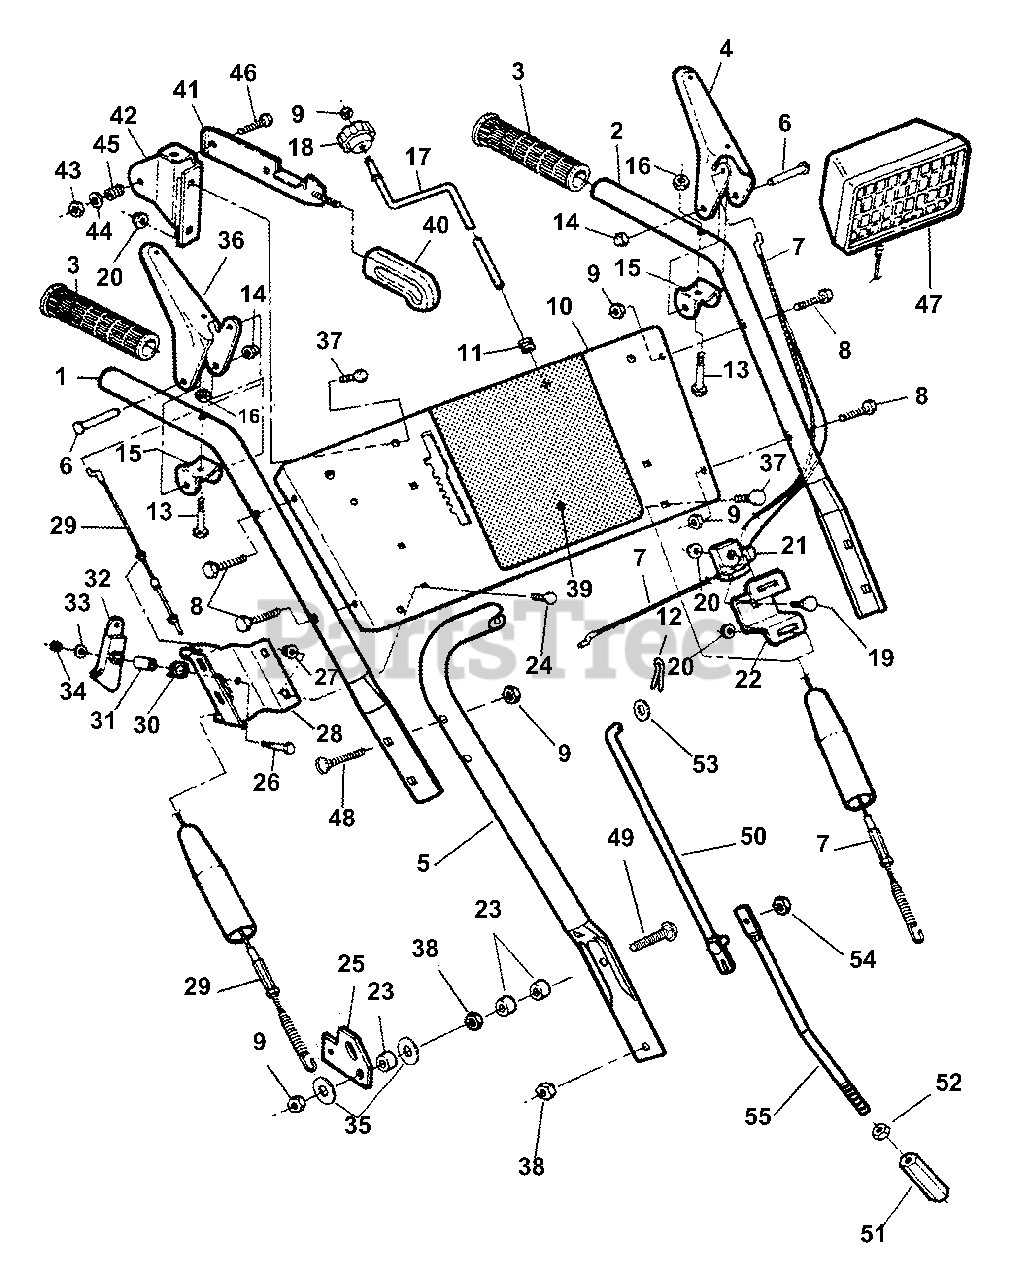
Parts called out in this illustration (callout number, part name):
1	BAR, Handle (Right Side)
2	BAR, Handle (Left Side)
3	GRIP, Handle
4	HANDLE, Left Side
5	HANDLE BAR, Lower
6	PIN, 1/4 x 1-7/8" Clevis
7	CABLE, Left Side Clutch
8	SCREW, 5/16-18 x 1-1/2" Hex Head Cap, Grade 5
9	NUT, 5/16-18 Hex Center Lock, Grade B
10	PANEL, Control
11	BUSHING
12	PIN, 1/8 x 1" Cotter
13	SCREW, 1/4-28 x 1-3/8" Hex Head Cap, Grade 5
14	NUT, 1/4" Push
15	BRACKET, Handle
16	NUT, 1/4-28 Hex Top Lock
17	CRANK, Chute
18	KNOB, Chute Crank
19	BOLT, 1/4-20 x 3/4" Short Neck Carriage, Grade 5
20	NUT, 1/4-20 Hex Flange Lock
21	GUIDE, Cable
22	BRACKET, Cable Guide Support
23	SPACER, 5/16"
24	BOLT, #10-24 x 1/2" Flat Head Carriage
25	LEVER, Clutch
26	SCREW, 1/4-20 x 1" Hex Head Cap, Grade 5
27	NUT, #10-24 Hex Flange Lock
28	BRACKET, Cam
29	CABLE, Auger (Right Side)
30	SPRING Cam Lock
31	SPACER
32	LOCK, Cam
33	WASHER, 1/4" Flat
34	NUT, 1/4-20 Hex Center Lock, Grade B or 5
35	WASHER, 5/16 x 1-1/4" Flat
36	HANDLE, Right Side
37	BOLT, 1/4-20 x 1/2" Short Neck Carriage, Grade 5
38	NUT, 5/16-18 Hex Flange Lock, Grade 5
39	DECAL, Instruction (see decal pages)
40	KNOB, Shift Handle
41	WELDMENT, Shift Handle
42	BRACKET, Shift Lever
43	NUT, 5/16-24 Hex Center Lock, Grade B
44	WASHER, 5/16" Flat
45	SPRING
46	SCREW, 5/16-24 x 1-3/4" Hex Head Cap, Grade 5
47	KIT, Light Assembly (Rectangular)
48	BOLT, 5/16-18 x 2", Square Neck Carriage, Grade 5
49	BOLT, 5/16-18 x 1-1/2" Square Neck Carriage, Grade 5
50	ROD, Upper Shift
51	NUT, 3/8-16 x 1-13/16 Connector
52	NUT, 3/8-16 Hex, Grade B
53	WASHER, 3/8" Flat
54	NUT, 1/4-20 Hex Nyloc
55	ROD, Lower Shift
